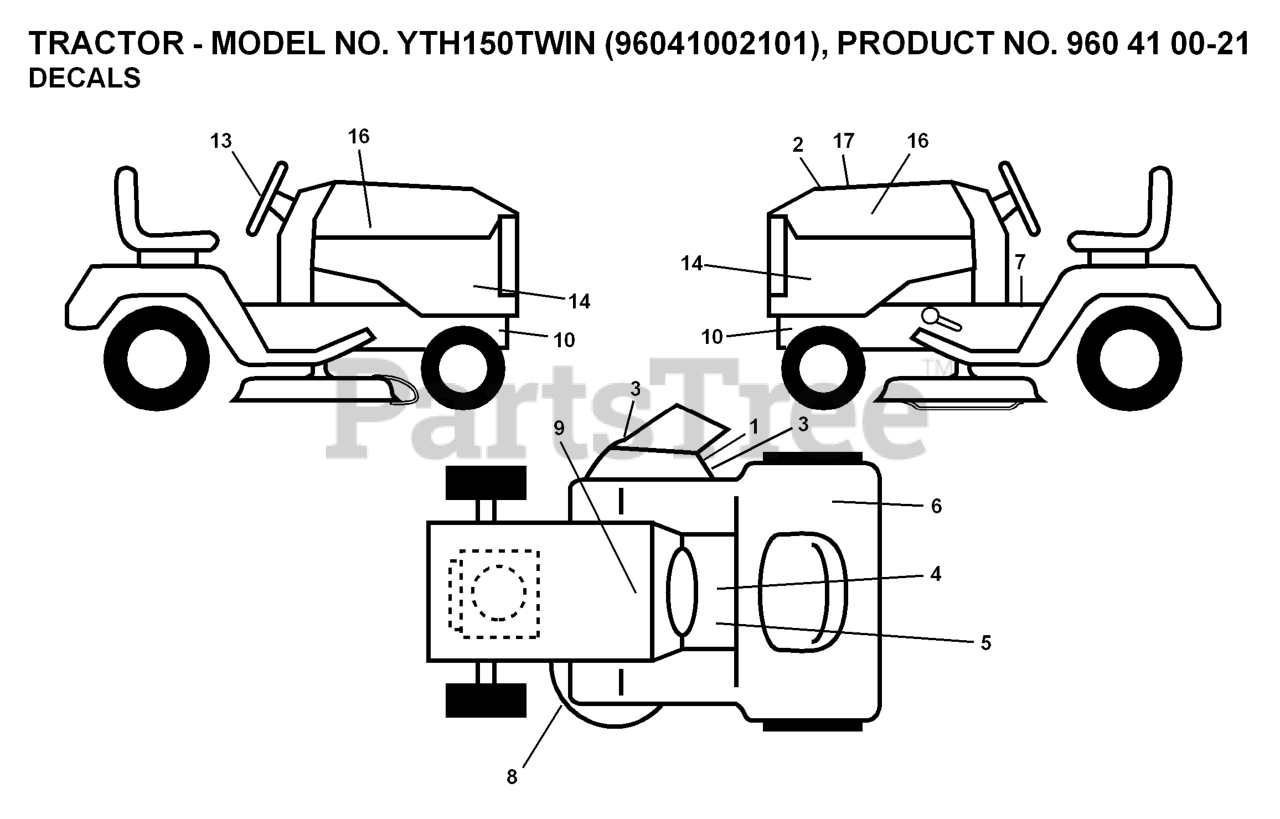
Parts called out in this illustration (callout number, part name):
1	DECAL.INTERNATIONL.CUTFINGER
2	DECAL.HOOD.TOP.INSERT.
3	DECAL, DEFLECT WARNING
4	DECAL PARK BRAKE
5	LABEL
6	Decal, Fender 100 DB/CE
7	DECAL
8	DECAL V BELT SCHEMATIC
9	DECAL BTRY SYMBOLS
13	DECAL.WHEEL.STRG.LGN.H
16	DECAL.HOOD.NAMELOGO.HUSQ
